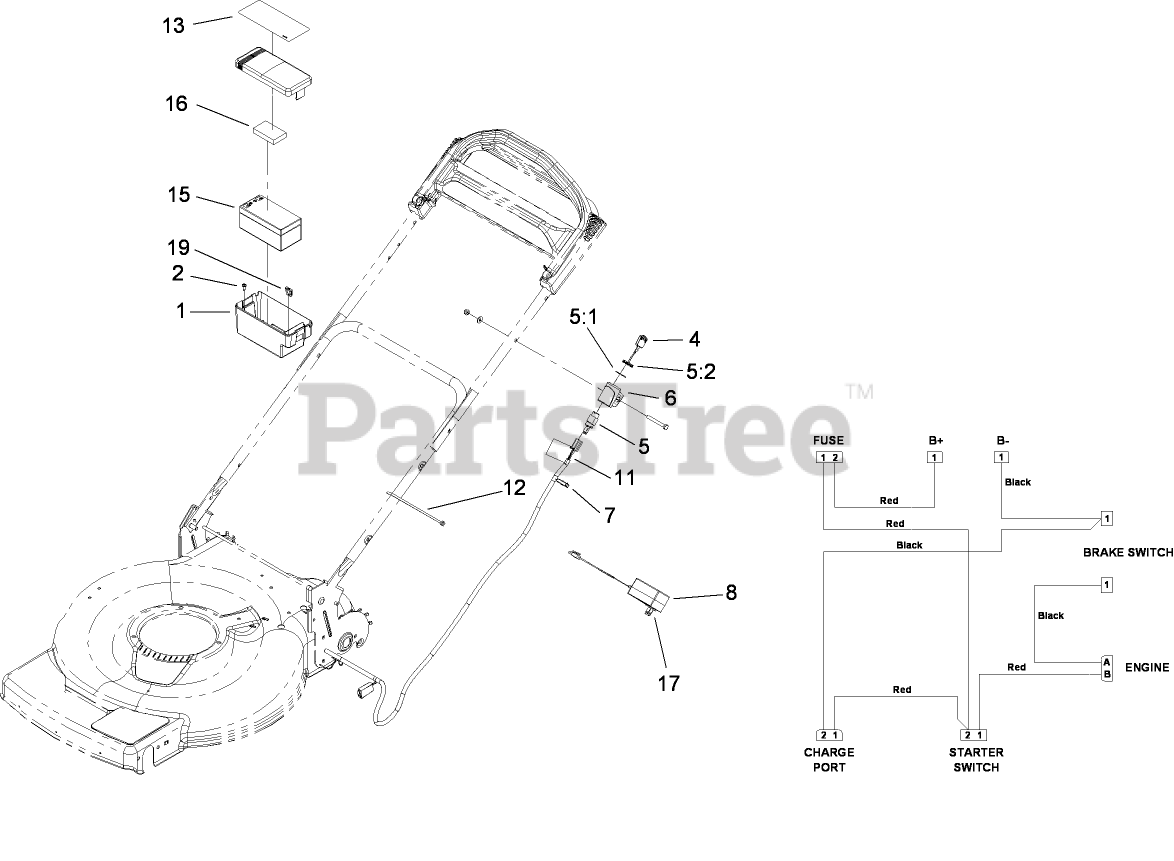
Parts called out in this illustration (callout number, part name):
1	BATTERY BOX ASM
2	SCREW-FORMING, THREAD
5	STARTER SWITCH ASM
5:1	WASHER-LOCK
5:2	NUT-HH
6	MOUNT-SWITCH
7	HARNESS-WIRE
8	CHARGER-EUROPEAN, 12V DC
11	DECAL-WARNING
12	TIE-CABLE
13	DECAL-INSTRUCTIONAL
15	BATTERY-WET
16	FOAM-BATTERY, TOP
17	ADAPTER-CHARGER
19	FUSE-40 AMP
